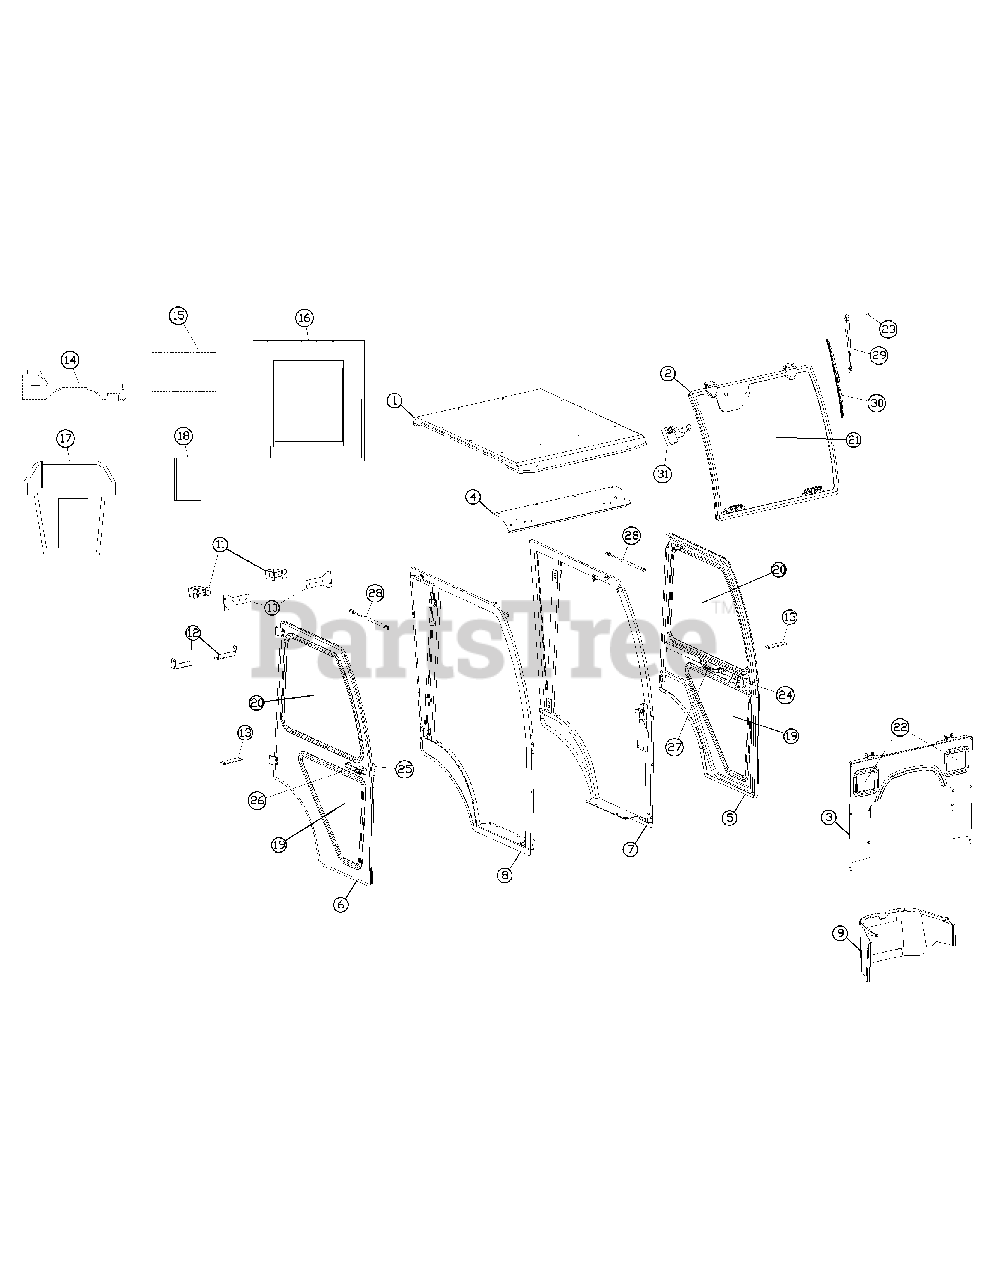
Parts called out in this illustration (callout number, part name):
1	ROOF ASSEMBLY CCY SC
2	WINDSHIELD CCY SC
3	WINDSHIELD COWL CCY SC
4	WINDSHIELD SUPPORT CCY SC
5	DOOR ASSEMBLY-L CCY SC
6	DOOR ASSEMBLY-R CCY SC
7	SIDE FRAME ASSEMBLY-L CCY SC
8	SIDE FRAME ASSEMBLY-R CCY SC
9	AIR INTAKE SHIELD CCY SC
10	AIR INTAKE SHIELD VINYL FILLER CCY SC
11	AIR INTAKE SHIELD SCREEN FILLER SKIN, CCY SC
12	REAR MOUNT BRACKET CCY SC
13	ROLL BAR BRACKET CCY SC
14	REAR MOUNTS CCY SC
15	LIGHT MOUNTS CCY SC
16	REAR CURTAIN CCY SC
17	UNDER SEAT FILLER CCY SC
18	SEAT FRAMER FILLER CCY SC
19	ACRYLIC, LOWER DOOR
20	UPPER DOOR WINDOW, CUB CADET Sc SERIES 3/16 GREEN TINT
21	GLASS WINDSHIELD 32 X 38 NO LOGO
22	ACRYLIC COWL WINDOWS CCY SC
23	BUTTON FOR WIPER MOTORS (THREADED)
24	INSIDE HANDLE ROTARY LATCH, RH
25	INSIDE HANDLE ROTARY LATCH, LH
26	OUTSIDE HANDLE, ROTARY LATCH
27	GRAB HANDLE (PLASTIC)
28	GAS SPRING (12")
29	WINDSHIELD WIPER ARM ADJUSTABLE LENGTH (14" - 16")
30	WIPER BLADE, 20" - FLEX
31	WINDSHIELD WIPER MOTOR 110 DEGREE
